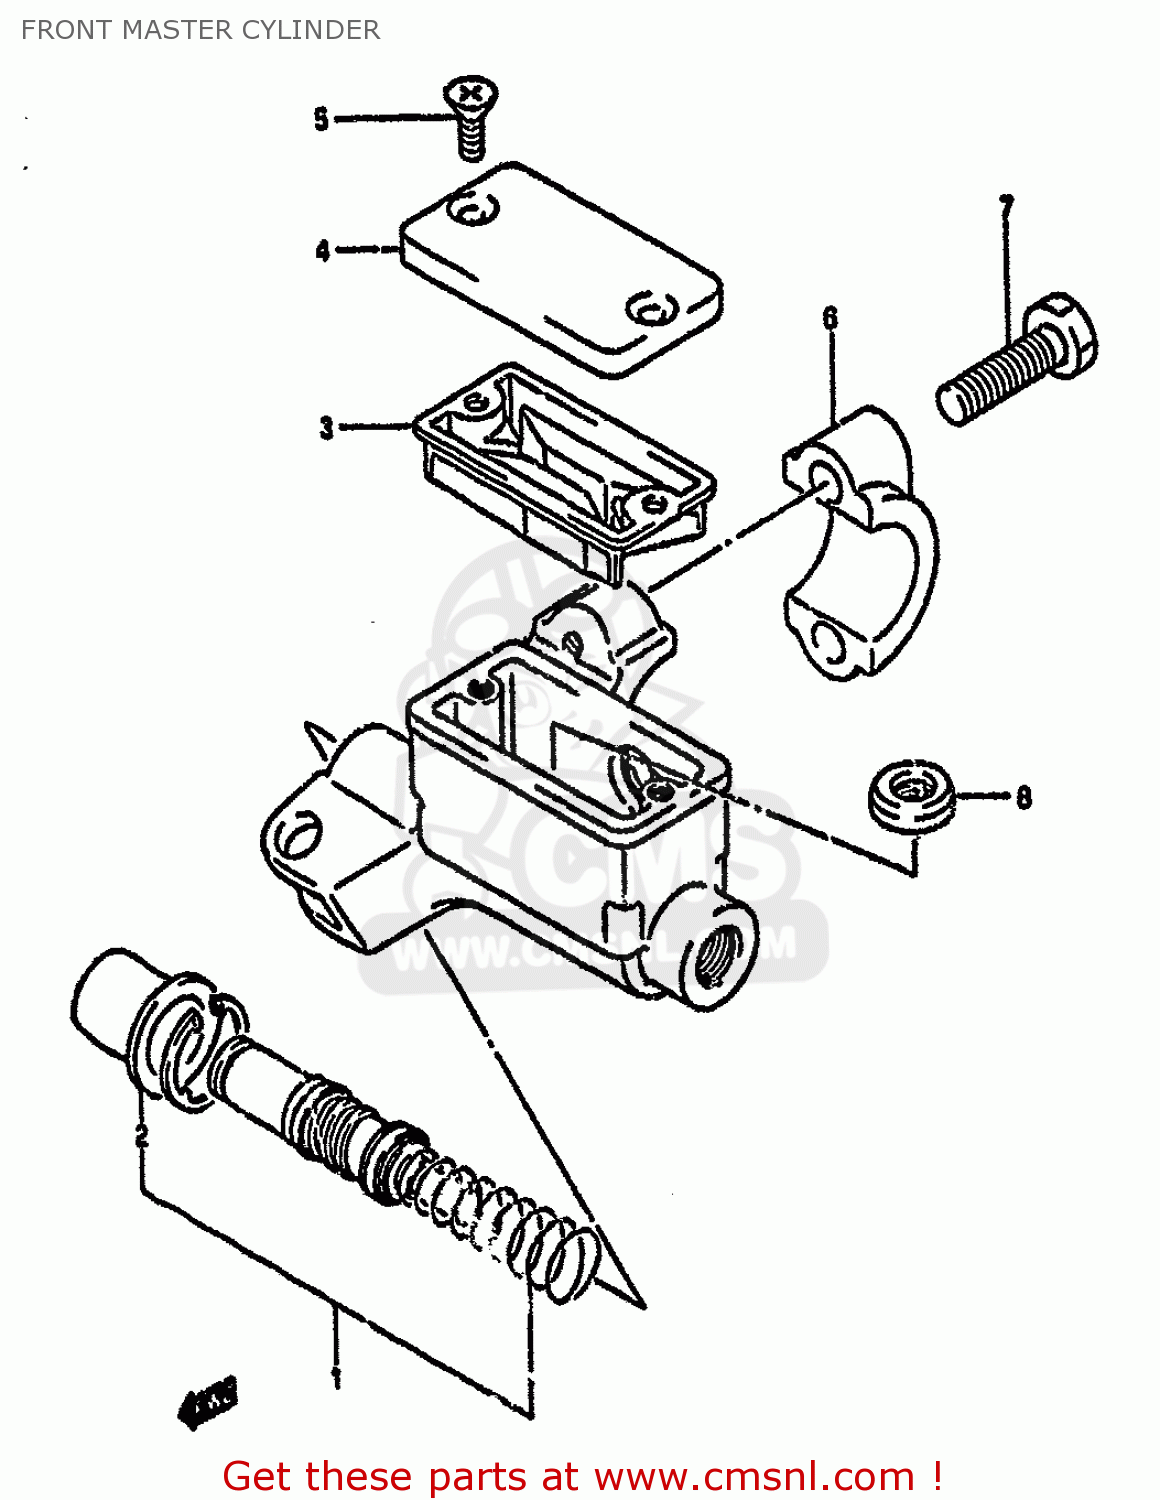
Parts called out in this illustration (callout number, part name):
1	PISTON & CUP SET
2	BOOT
3	DIAPHRAGM
4	CAP
5	SCREW
6	HOLDER
7	BOLT
8	SEPARATOR
